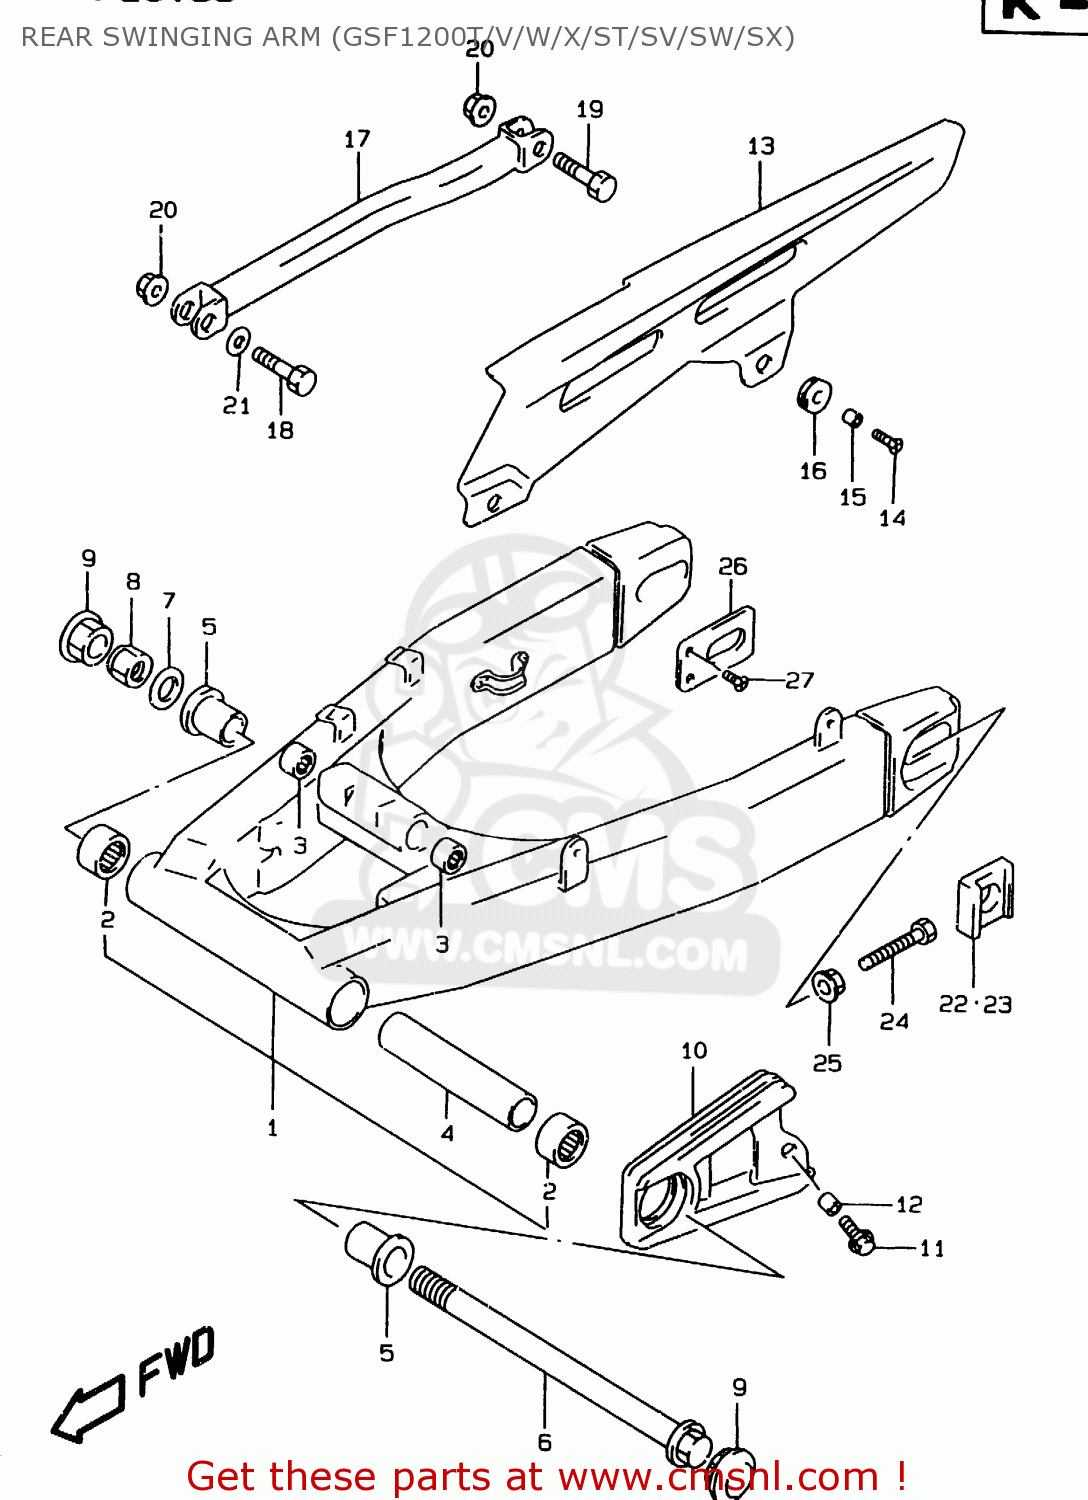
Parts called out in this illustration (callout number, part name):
1	SWINGINGARM ASSY,RR
2	BEARING(25X33X35)
3	BEARING(17X24X25)
4	SPACER,RR SWGARM PIVOT CTR
5	SPACER,RR SWGARM PIVOT BERRING
6	SHAFT,RR SWINGINGARM PIVOT
7	WASHER(18.5X28X2.6)
8	NUT
9	CAP,FRAME PIVOT
10	BUFFER,CHAIN TOUCH DEFENSE
11	BOLT 6X20,WITH PLAIN WASHER
12	SPACER(6.5X10X7)
13	CASE,CHAIN
14	SCREW (6X16)
15	SPACER(6.2X8.3X6.1)
16	CUSHION
17	TORQUELINK,RR
18	BOLT(10X39)
19	BOLT(10X37)
20	NUT
21	WASHER(12.5X20X1)
22	WASHER,CHAIN ADJUSTER
23	WASHER,CHAIN ADJUSTER
24	BOLT(8X50)
25	NUT
26	PLATE,RR SWING ARM BRKT
27	SCREW 6X10
